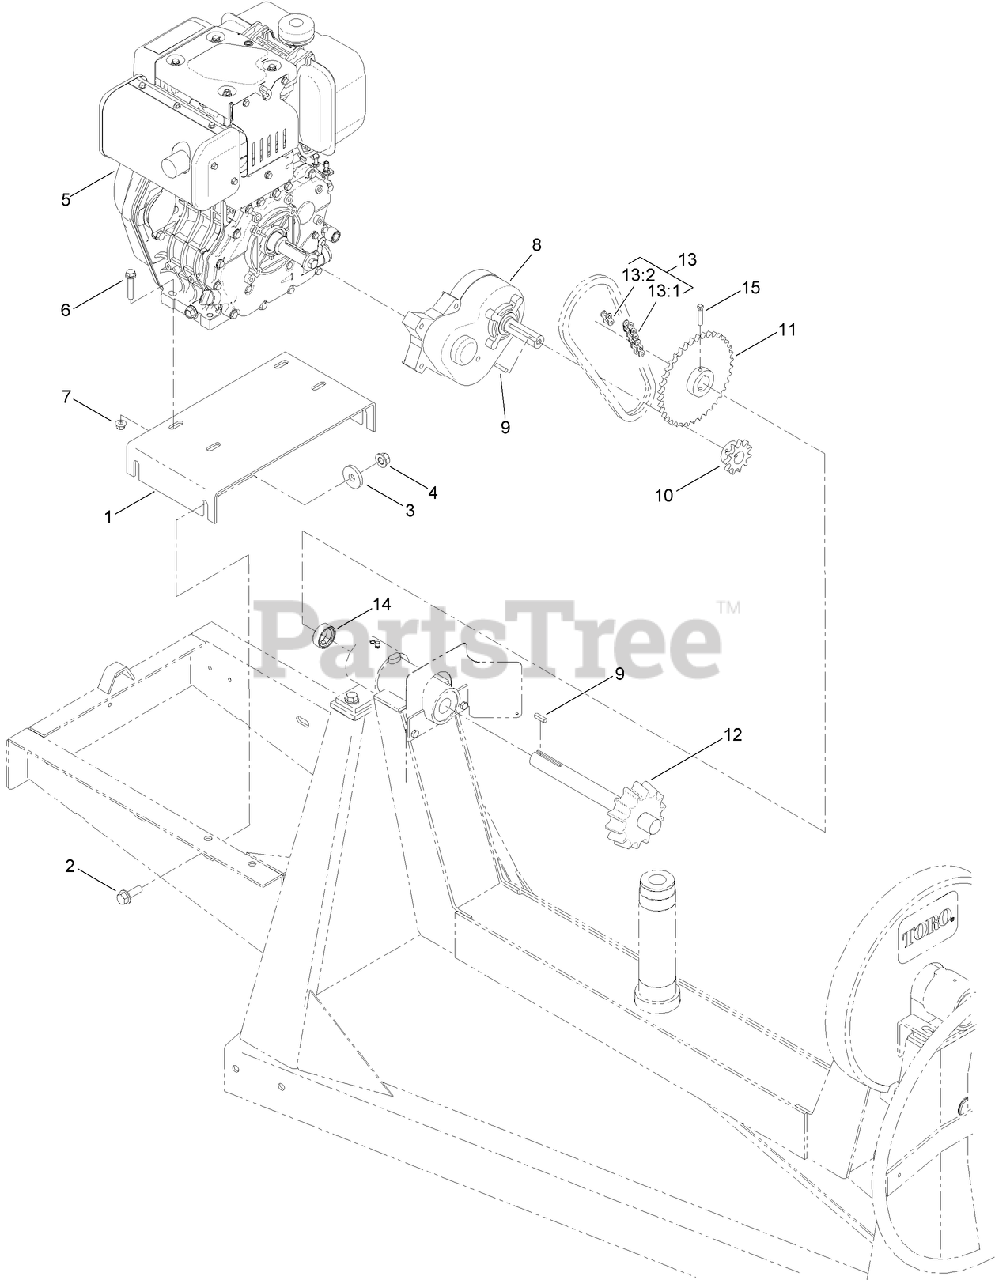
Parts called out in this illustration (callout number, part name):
1	BASE-MOTOR
2	SCREW-HHF
3	WASHER-FLAT
4	NUT-LOCK
5	ENGINE-DIESEL
6	SCREW-HHF
7	NUT-HF, NI
8	REDUCER-GEAR
10	SPROCKET
11	SPROCKET
12	SHAFT-DRIVE
13	CHAIN SET
13:1	CHAIN
13:2	LINK-CONNECTING, NO. 50
14	COLLAR-LOCKING
15	SCREW-SET
